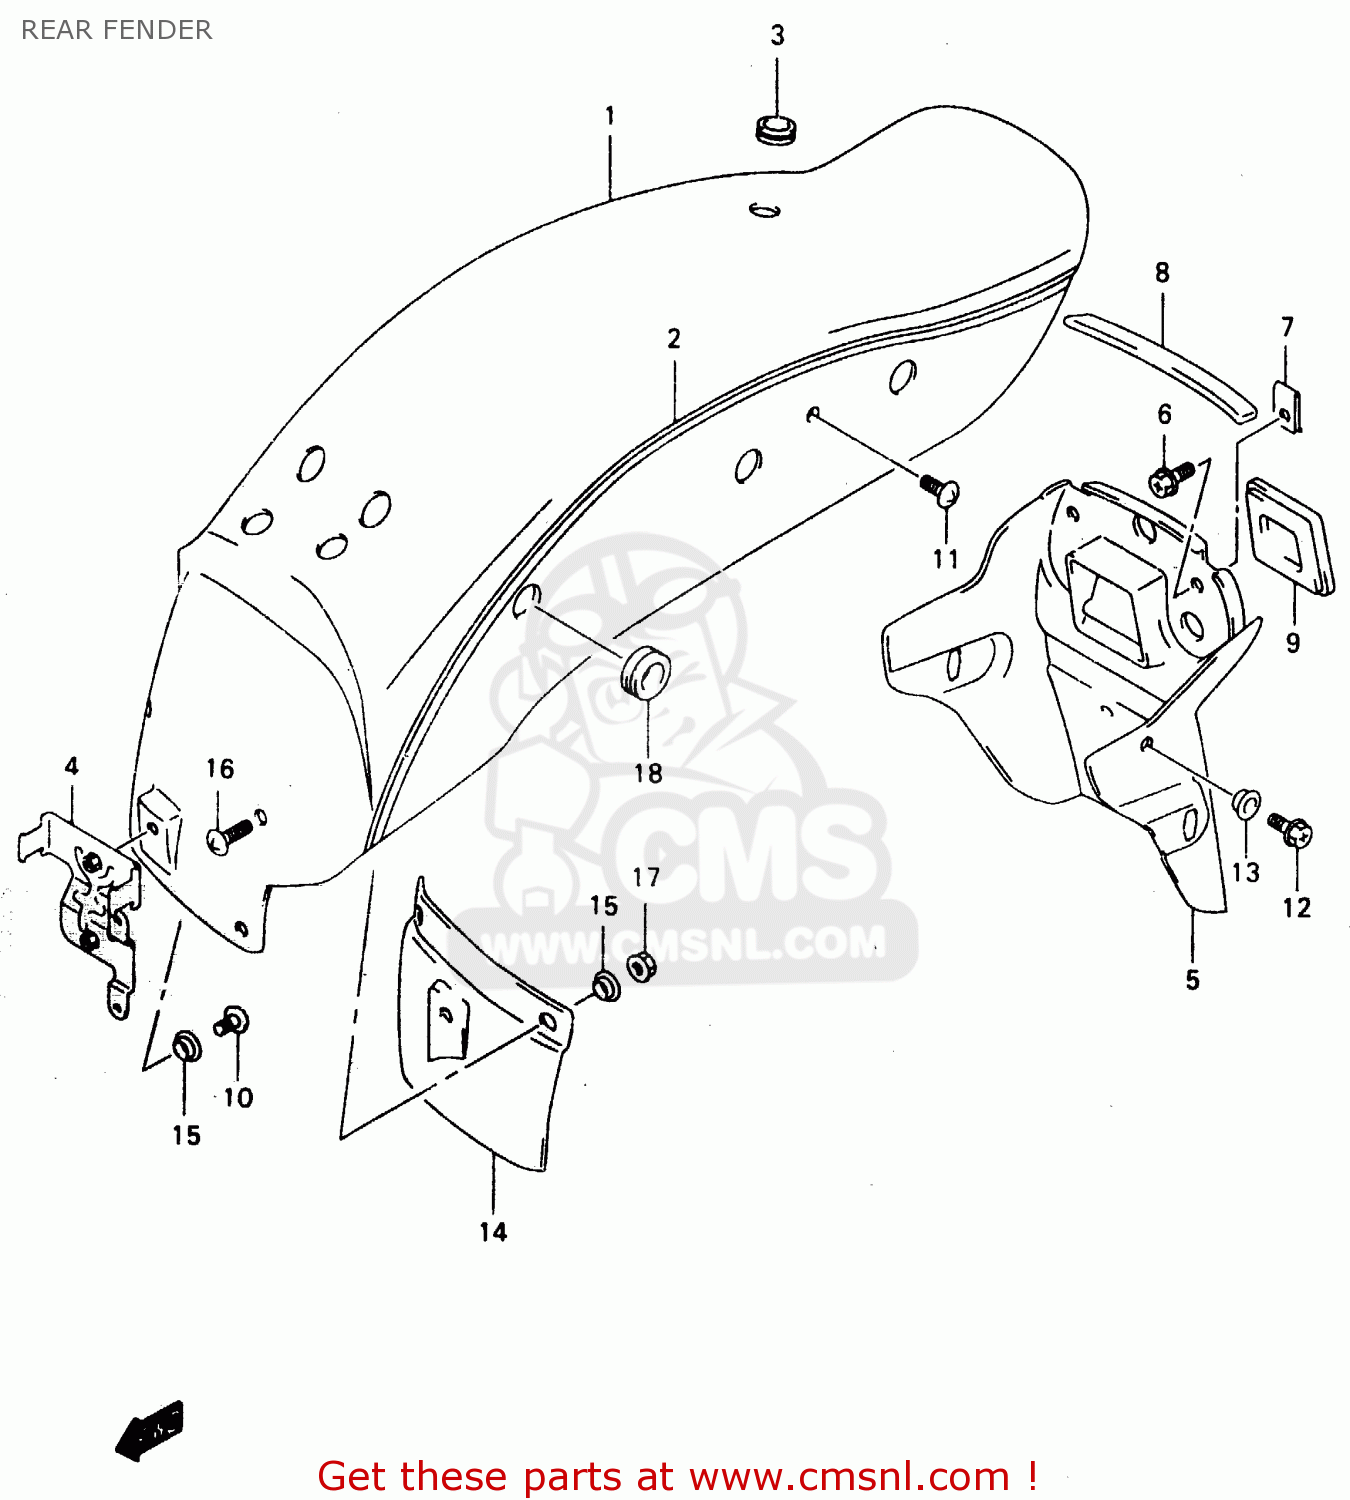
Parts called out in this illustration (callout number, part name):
1	FENDER,RR
2	TAPE SET,RR FENDER
3	CUSHION
4	BRACKET,RR FENDER
5	EXTENSION,RR FENDER
6	SCREW
7	PLATE,FRAME COVER
8	CUSHION,RR FENDER EXTENSION
9	CAP,RR FENDER EXTENSION
10	SCREW
11	SCREW 6X12
12	BOLT
13	WASHER
14	MUDGUARD,RR FENDER
15	WASHER
16	SCREW
17	NUT
18	CUSHION,RR FENDER
